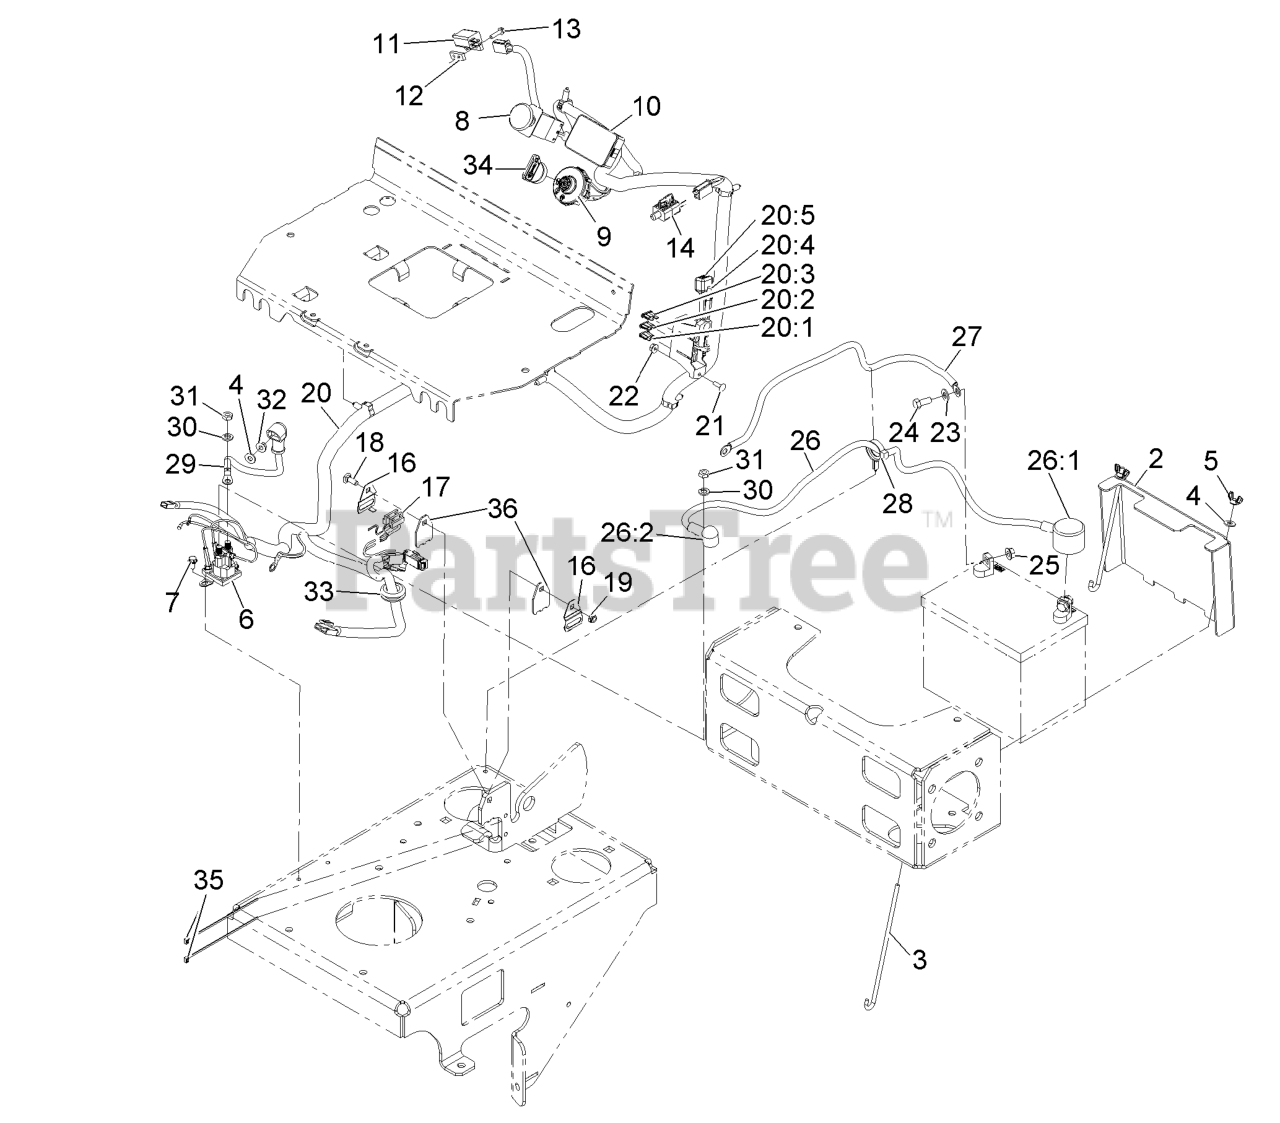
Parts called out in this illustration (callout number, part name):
2	COVER-BATTERY
3	BOLT-HOLDDOWN
4	WASHER-FLAT
5	WINGNUT
6	SOLENOID
7	SCREW-HWH
8	SWITCH-PTO, ON-ON
10	MODULE-HOUR METER
11	SWITCH-CLOSED, NORMALLY
12	PLATE-TAPPED
13	SCREW-HWH
14	SWITCH-PLUNGER, NC, SPST
16	CLAMP-SWITCH
17	HARNESS-SWITCH, REED
18	BOLT-CARR
19	NUT-LOCK, NI
20	HARNESS-WIRE
20:1	FUSE-BLADE, 30 AMP
20:2	FUSE-BLADE, 25 AMP
20:3	FUSE-BLADE, 10 AMP
20:4	CAP-PLUG
21	SCREW-CARR
23	WASHER-PLAIN
24	SCREW-HH
25	NUT-HHF, SMOOTH
26	ASM,POSITIVE BATTERY CABL
26:1	INSULATOR-BATTERY
26:2	INSULATOR-SOLENOID
27	CABLE-BATTERY, NEGATIVE
28	CLAMP-HOSE
29	CABLE-BATTERY, RED
30	WASHER-LOCK
31	NUT-JAM
33	GROMMET
34	KEY-IGNITION
35	TIE-CABLE
36	PLATE-SPACER
